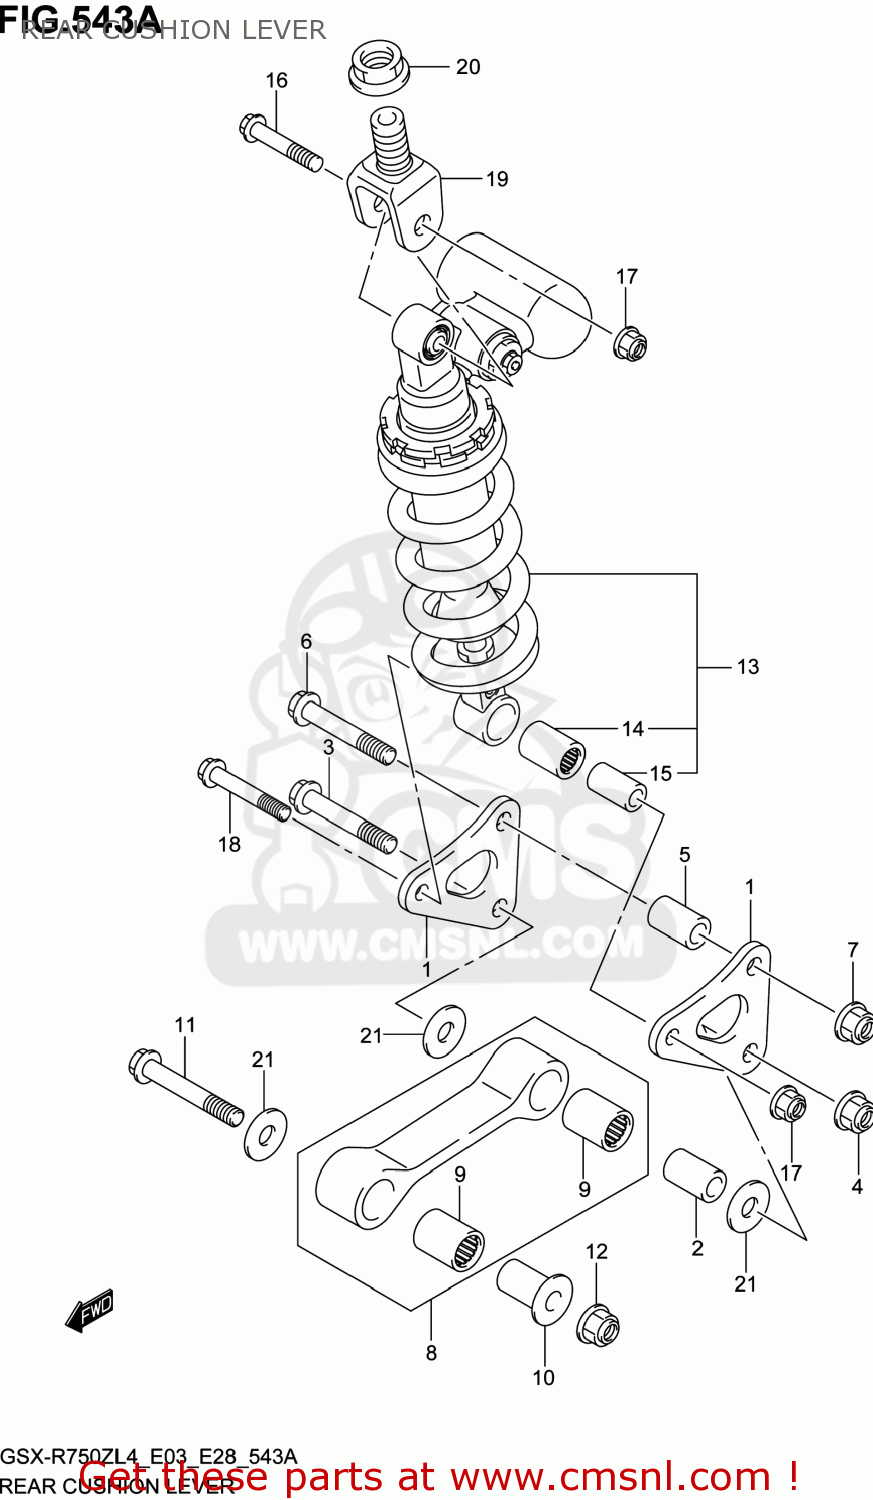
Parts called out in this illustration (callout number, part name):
1	LEVER,RR CUSHION
2	SPACER,RR CUSHION LEVER FR
3	BOLT,RR CUSHION LEVER
4	NUT
5	SPACER,RR CUSHION LEVER FR
6	BOLT,RR CUSHION LEVER
7	NUT
8	ROD,RR CUSHION
9	BEARING(20X27X32)
10	SPACER,RR CUSHION ROD FR
11	BOLT,RR CUSHION ROD
12	NUT
13	ABSORBER ASSY,REAR SHOCK
14	BEARING(17X24X32)
15	SPACER,RR SHOCK ABS LWR
16	BOLT(10X55)
17	NUT
18	BOLT,RR SHOCK ABSORBER LWR
19	BRACKET,RR SHOCK ABSORBER UPR
20	NUT,RR SHOCK ABS BRACKET
21	WASHER(12X34X1)
